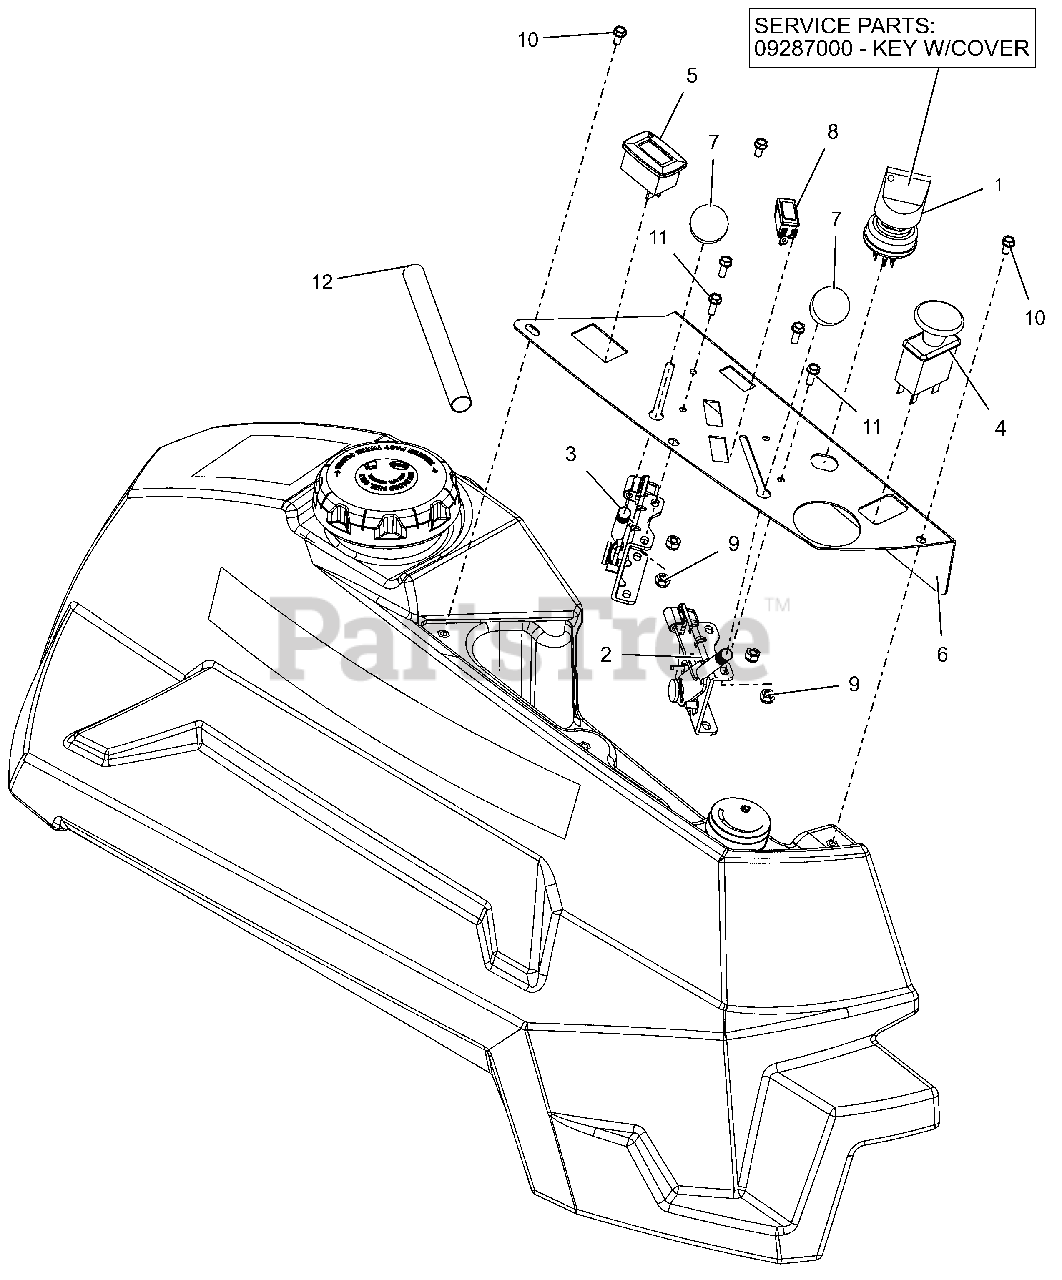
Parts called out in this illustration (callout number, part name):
1	SWITCH, IGNITION
1	KEY, W/ SHIELD
2	CABLE, PRO-CTRL 43.00"
3	CABLE, PRO-CTRL 46.00"
4	SWITCH, CLUTCH
5	METER, HOUR W/MAINTENANCE
6	PT400 CONTROL PANEL - RED
7	KNOB-CONTROL-BLACK .38-16X.50
8	LIGHT,INDICATOR
9	@NUT-LK-NYL 10-24 W/INSRT YWZC
10	SCR-MCH 10-24X.38 HWHSTAINLESS
11	@SCR-MCH 10-24X.50 HWH YWZC
12	SLEEVE, THERMAL 6"
